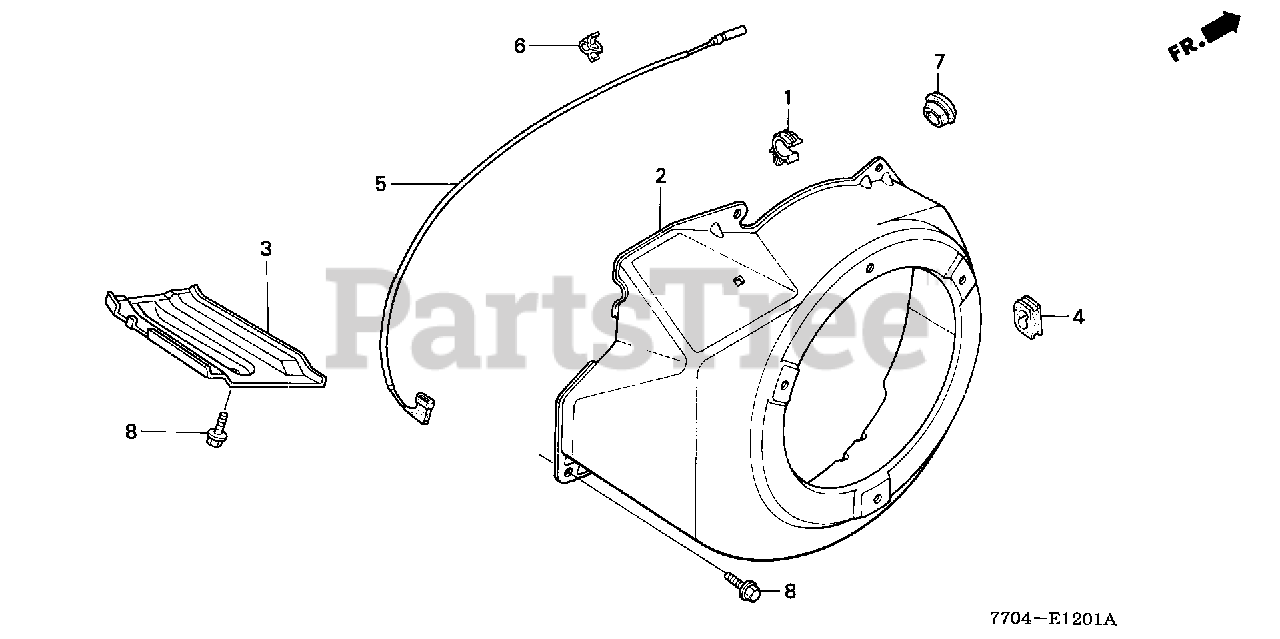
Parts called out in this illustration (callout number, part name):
1	CLIP, TUBE
2	COVER, FAN *R280* (POWER RED)
4	GROMMET, WIRE
5	WIRE, STOP SWITCH (370MM)
6	HOLDER, STOP SWITCH WIRE
7	GROMMET, DRAIN HOLE
8	BOLT, FLANGE (6X12) (CT200)
